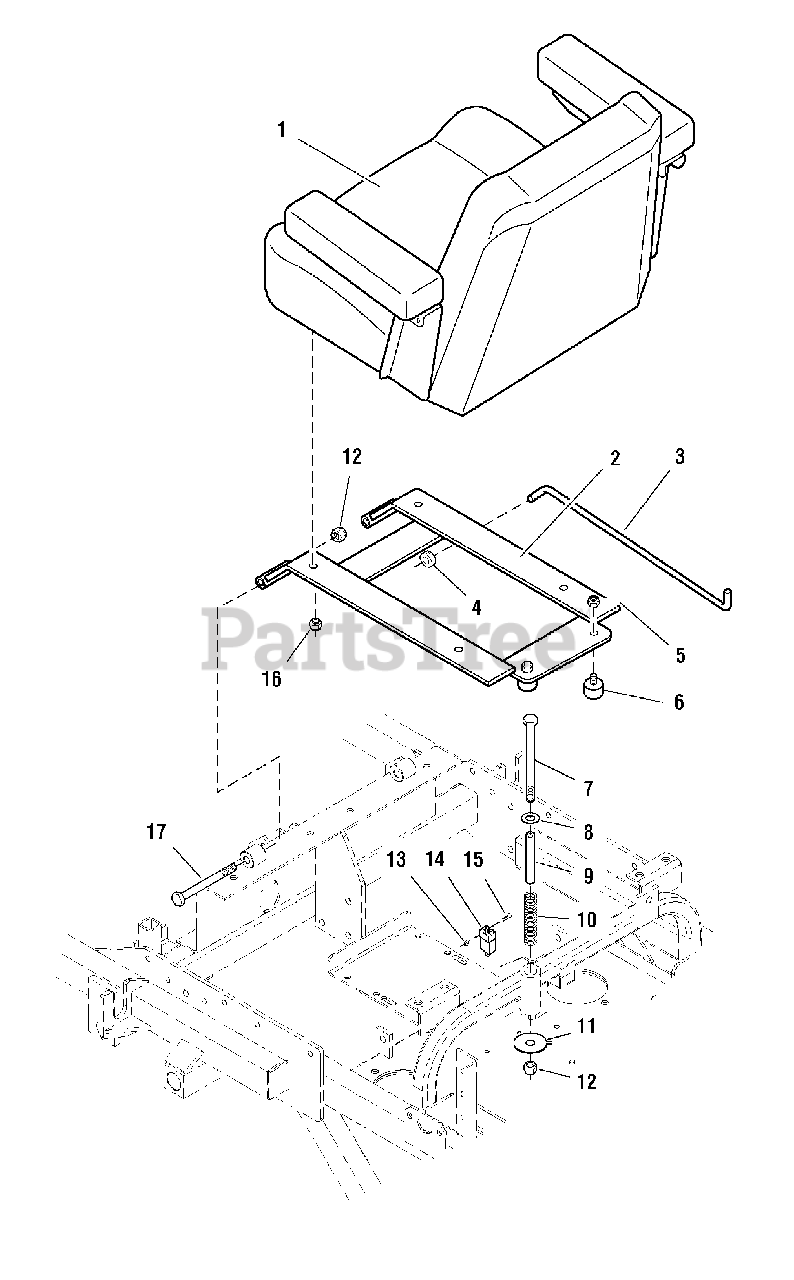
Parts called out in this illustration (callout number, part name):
1	SEAT, Derby (complete)
3	SEAT STOP ROD
4	COLLAR, 5/16 Set
5	NUT, Hex, Nylon Lock, 1/4-20
6	RUBBER BUMPER
7	CAPSCREW, Hex Hd, 3/8-16 x 6
8	WASHER, 3/8
9	SPACER, .38 x .50 x 5.06
10	SPRING, Compression
11	WASHER, 3/8 x 2
12	NUT, Hex, Nylon Lock, 3/8-16
13	NUT, Hex, #10-24
14	SWITCH (see electrical schematic)
15	SCREW, #10-24 x 1/2
16	NUT, Hex, Nylon Lock, 5/16-18
17	CAPSCREW, Hex Hd, 3/8-16 x 4
